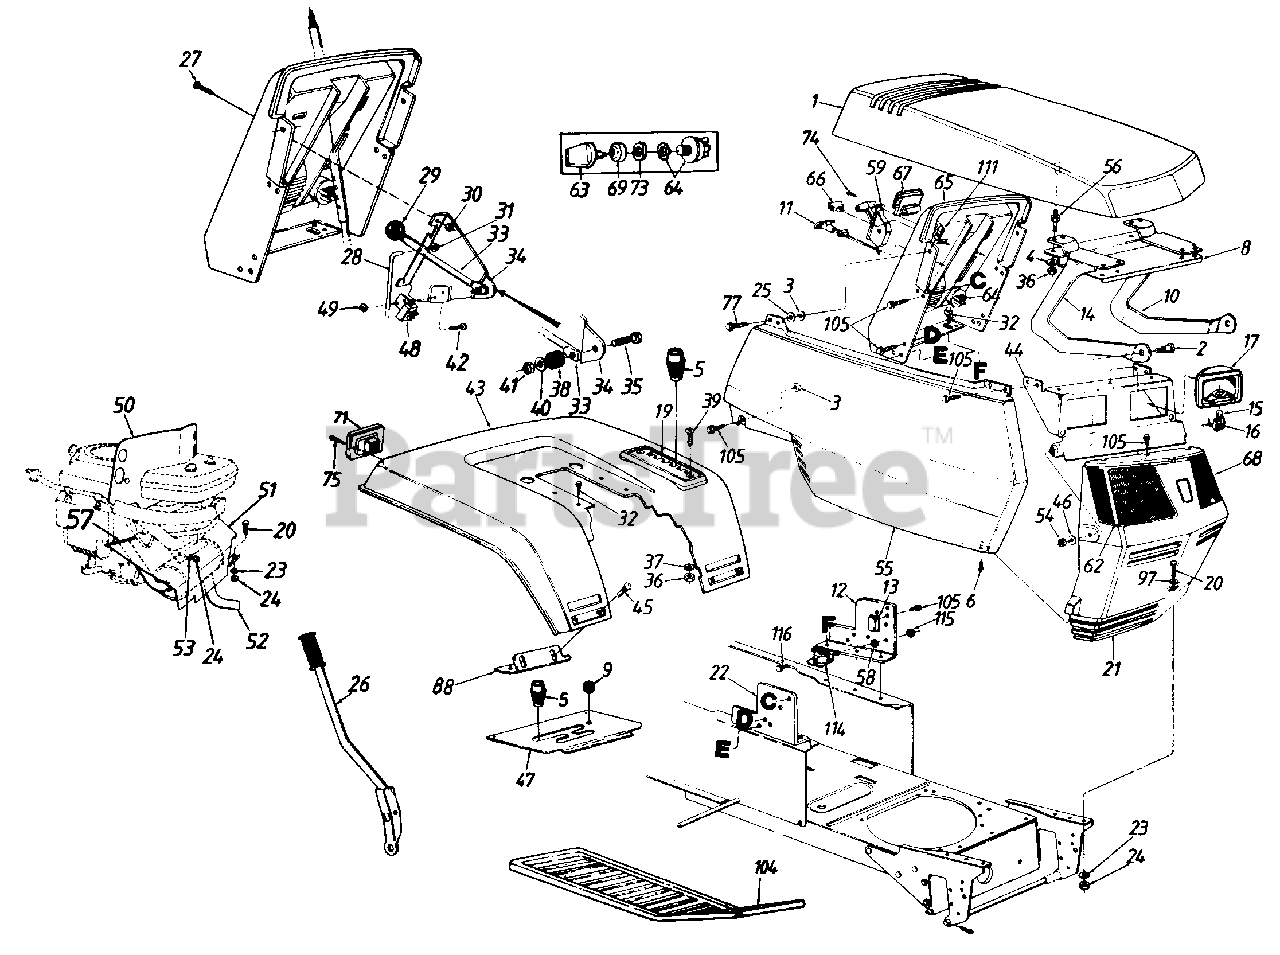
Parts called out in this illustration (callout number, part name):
3	Bolt Retainer 1/4" I.D.
4	Bell-Wash. .265" I.D. x .75" O.D
5	Shift Knob
6	Truss Mach. B-Tap Scr. #10 x .5" Lg.
8	Hood Reinforcement
9	Ball Knob Brake
10	Hood Hinge L.H.
11	Choke Control
12	Dash Support Brkt. L.H.
13	Circuit Breaker
14	Hood Hinge R.H.
15	Lamp
16	Twist Lock Lamp Socket
17	Headlight Housing
19	Speed Control Index Brkt.
20	Hex Bolt 5/16-18 x .75" Lg.
23	L-Wash. 5/16" I.D.*
24	Hex Nut 5/16-18 Thd.
25	Fl-Wash. 1/4" I.D. x .93" O.D.
26	Lift Handle Ass'y.
27	Truss Mach. Scr. 1/4-20 x .51' Lg.
28	Deck Control Rod
29	Knob Blade Clutch
30	Hex Sems Nut 1/4-20 Thd.
31	Push Cap
32	Hex Wash. Hd. AB-Tap Scr. 5/16 x .75" Lg.
33	PTO Lever
34	Deck Clutch Cont. Brkt.
35	Hex Bolt 1/4-20 x 1.25" Lg.
36	Hex Nut 1/4-20 Thd.
37	L-Wash. 1/4" I.D.
38	Rubber Washer
39	Truss Mach. Scr. 1/4-20 x .621" Lg.
40	Fl-Wash. .281" I.D. x .73"
41	Hex L-Nut 1/4-20 Thd.
42	Truss Mach. Scr. #10-24 x .5" Lg.
43	629 Rear Fender
46	Fl-Wash. .328" I.D. x .68" O.D.
47	Transmission Panel
48	Safety Switch
49	Hex Nut #10-24 Thd.
50	Top Heat Shield
51	Front Heat Shield
52	Muffler
53	L-Wash. 5/16" I.D.
54	Hex Cent. L-Nut 5/16-18 Thd.
55	Side Cover R.H.
56	Double Ended Stud 1/4-20 Thd.
57	Trim Strip 12" Lg.
58	Ext. L-Wash. 1/4" I.D.
59	Throttle Control Box Ass'y.
62	Lens R.H.
63	Ignition Key
64	Ignition Switch
65	Dash Panel
66	Light Switch
67	Ammeter
68	Lens L.H.
69	Ignition Switch Cap
71	Taillight Ass'y.
73	Ignition Switch Nut
74	Truss Mach. AB-Tap Scr. #10 x .5" Lg.
75	Truss Hd. AB-Tap Scr. #6 x .62" Lg.
77	Hex Wash. Hd. Tap Scr. 1/4 x .75" Lg.
104	Foot Pad
105	Hex Tap Scr. 1/4-20 x .5" Lg.
111	Speed Nut 1/4-20 Thd.
114	N Solenoid
115	Hex Sems Nut 1/4-20 Thd.
116	Hex Bolt 1/4-20 x .5" Lg.
